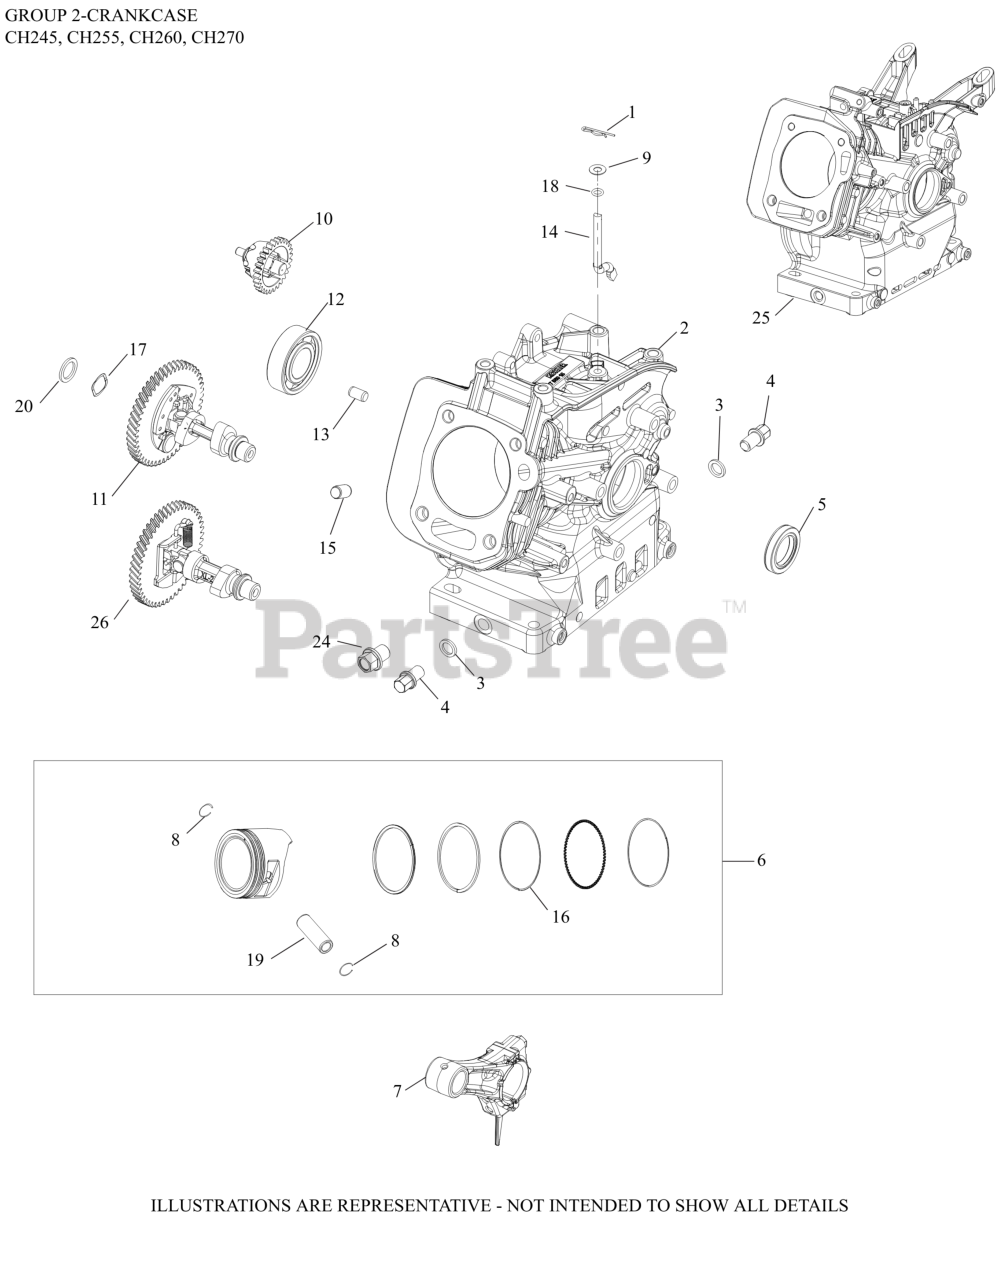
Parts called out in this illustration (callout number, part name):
1	CLIP, GOVERNOR SHAFT
2	CRANKCASE
3	WASHER, DRAIN PLUG
4	KIT, DRAIN PLUG
6	KIT, PISTON (STD)
7	ROD, CONNECTING ASSEMBLY
9	WASHER, FLAT (DIA 13MM O.D.)-(#1446830S)
10	GOVERNOR ASSEMBLY
14	SHAFT, GOVERNOR CROSS
15	DOWEL, CYLINDER HEAD-(#1438013S)
19	PIN, PISTON
